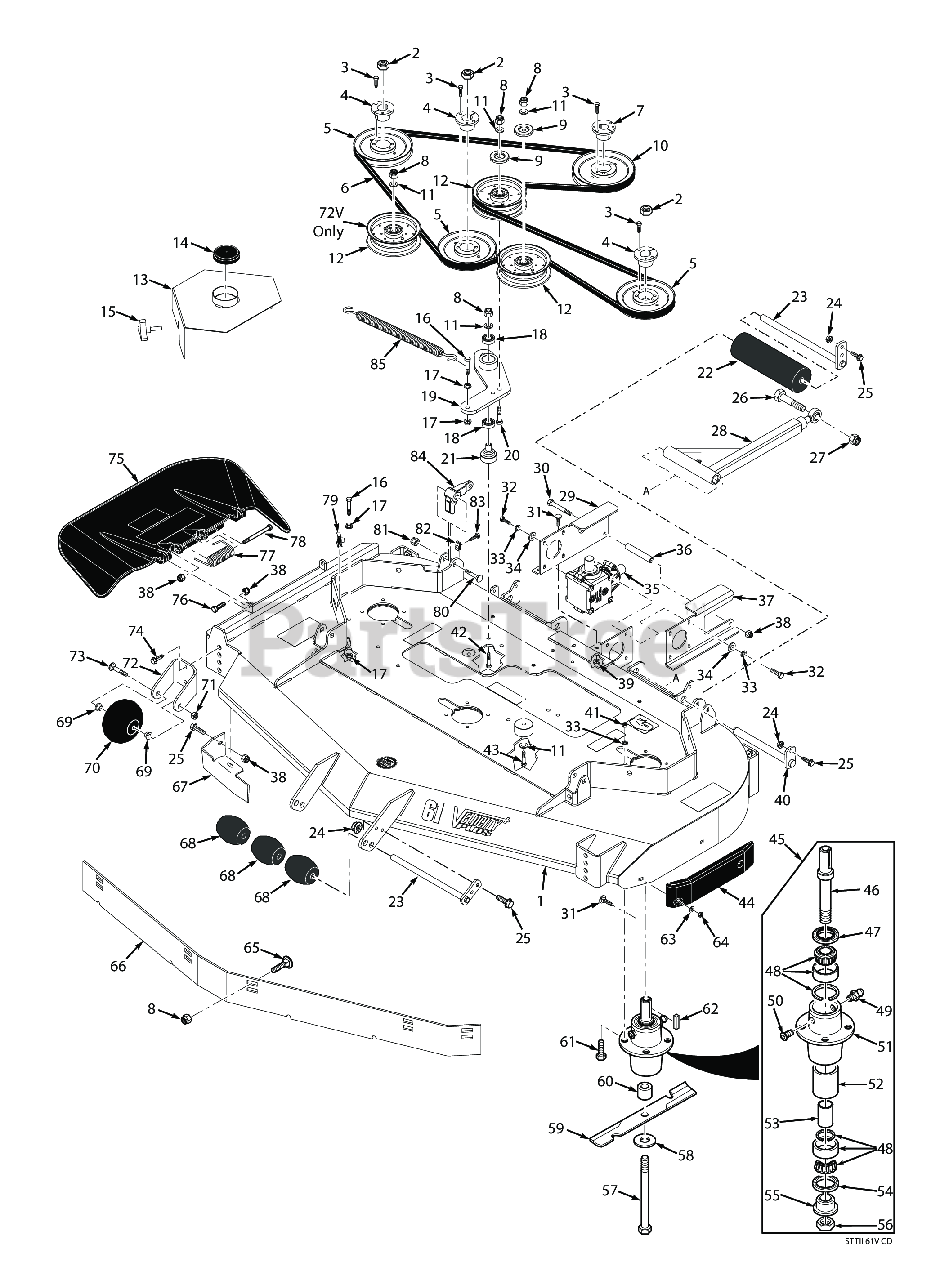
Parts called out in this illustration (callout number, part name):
1	Cutter Deck w/Decals - 61V
1	Cutter Deck w/Decals - 72V
2	Hex Locknut, Elastic Stop, 3/8-16
3	Bolt, Hex Head 1/4-20 x 1" Grade 8 Black
4	Hub, Tapered 1-1/8" Bore
5	Pulley, 6.35 O.D. (Diesel Engine)
5	Pulley, 6.95" O.D. - 72"
6	Belt, Cutter Deck Drive - Kubota
6	Belt, Cutter Deck Drive, 72"
7	TAPERED HUB, 1.00" BORE
8	HEX NUT, ELASTIC STOP LOCK, 3/8-16
9	Quick Pin, 5/16" Dia.
10	Pulley, 6.75 O.D. - 61"
10	Pulley, 6.35 O.D. (Diesel Engine)
10	Pulley, 5.75 O.D. (Gasoline Engines)
11	Flatwasher, 3/8 (.391 x .938 x .105 HD) Grade 8
12	Idler Pulley, Belt Clutch
13	Belt Cover, 61V
13	Belt Cover, LH 72V
13	Belt Cover, RH 72V
15	Knob, w/stud 3/8-16 x 1-1/4"
16	Bolt, Hex Head 3/8-16 x 1-1/2" Grade 8 Black
17	NUT, 3/8-16 SERRATED FLANGE HEX HEAD
18	BEARINGS, BALL, NEUTRAL RETURN
19	Idler Arm, Cutter Deck
20	Capscrew, Hex Head 3/8-16 x 2.75"
21	Pivot, Idler - Short
22	Wheel, Anti-ScalpRelief Fitting, Tapered Spindle
23	Shaft Weldment, Guide Roller
24	Nut, Serrated Flange 5/16-18 (Right Front Engine Mounting, Briggs and Kohler Only)
25	Bolt, Heax Head 5/16-18 x 1" (48V / 52V)
26	BOLT, HEX HEAD 5/8-11 X 4-1/2"
27	HEX LOCKNUT, ELASTIC STOP, 5/8-11
28	Push Arm (Includes 64,60,62)
29	Mounting Plate, RH Gearbox
30	Bolt, 5/16-18 x 4-3/4" Hex Head
31	Bolt, 5/16-18 x .75 RHSN Carriage
32	Bolt, Heax Head 5/16-18 x 1" (48V / 52V)
33	Lockwasher, 5/16 (.317 x .586 x .078) Helical Spring
34	Flatwasher, 5/16-.375 x .875 x .083 (35BV & 37BV-EFI)
35	Gearbox Assembly, Deck Drive
36	Spacer, Gearbox Mount
37	Mounting Plate, LH Gearbox
38	HEX NUT, ELASTIC STOP LOCK, 5/16-18
39	Nut, Serrated Flange 5/16-18 (Right Front Engine Mounting, Briggs and Kohler Only)
40	Shaft Weldment, Pusharm
41	Lock Nut, 5/16-18 Elastic Stop Grade 8
42	Bolt, Hex Head 3/8-16 x 3" - 52"
43	Capscrew, Hex Head 3/8-16 x 3-3/4"
44	Pad, Deck Wear
45	Cutter Spindle Assembly
46	Spindle Shaft, Tapered Brng
47	SEAL, 2.00 O.D. X 1.50 BORE
48	Tapered Bearing Set (Two Bearings W/Race)
49	GREASE FITTING, STR. 1/4-28 SELF TAP.
50	RELIEF FITTING, TAPERED BEARING SPINDLE
51	Housing, Spindle
52	Spacer, Outside, Cutter Spindle
53	SLEEVE, CUTTER SPINDLE
54	Seal, 2.00" O.D. x 1.625" Bore
55	SPINDLE BUSHING, BOTTOM
56	Nut , Spec ial 1 -1/ 1 6 - 1 8
57	BOLT, HEX HEAD, 5/8-11 X 9-1/2 GR.5
58	Flatwasher, 5/8-.688 x 1-3/4 x .134 HD
59	Cutter Blade, 21" Standard
59	Cutter Blade, 21" (35BV & 37BV-EFI)
59	Cutter Blade, 24.5" 72"
60	Spacer, Spindle Bottom
61	Bolt, Hex Head 5/16-18 x 1-3/4" Grade 8
62	Key, 1/4 x 1/4 x 2.0"
63	Flatwasher, 5/16-.344 x .688 x .065 (48V / 52V)
64	Nut, Center Lock, 5/16-18(32)
65	Carriage Bolt, 3/8-16 x 1.0"
66	Baffle Custom-Cut, 61V (7-Position)
66	Baffle, Custom Cut - 72V
67	Turbo Baffle, Bolt On
67	Baffle, Turbo - 72V
68	Wheel, Anti-Scalp
69	Bushing, .376" I.D. Oilite
70	Bolt, Carriage 3/8-16 x 4"
71	Bolt, Hex Head 3/8-16 x 1" Ser. Flg.
72	Bracket, Anti-Scalp Wheel
73	Bolt, Hex Head 3/8-16 x 3-1/2"
74	Capscrew, 3/8-16 x 1.0" Serrated Flange Hex Hd
75	Discharge Chute Advantage - Large
75	Discharge Chute Assy. 72V
76	Bolt, Hex Head 5/16-18 x 1-1/2" - Front
77	Spring, Discharge Chute
78	Bolt, 5/16-18 x 4-3/4" Hex Head
79	U-Nut, 3/8-16
80	Bolt, Carriage 7/16-14 x 2-1/4"
81	HEX LOCKNUT, ELASTIC STOP, 7/16-14
82	U-Nut, 3/8-16 (short)
83	Bolt, Hex Head 3/8-16 x 2" Special Lock
84	Lever, Deck Level
85	Spring, Cutter Deck
